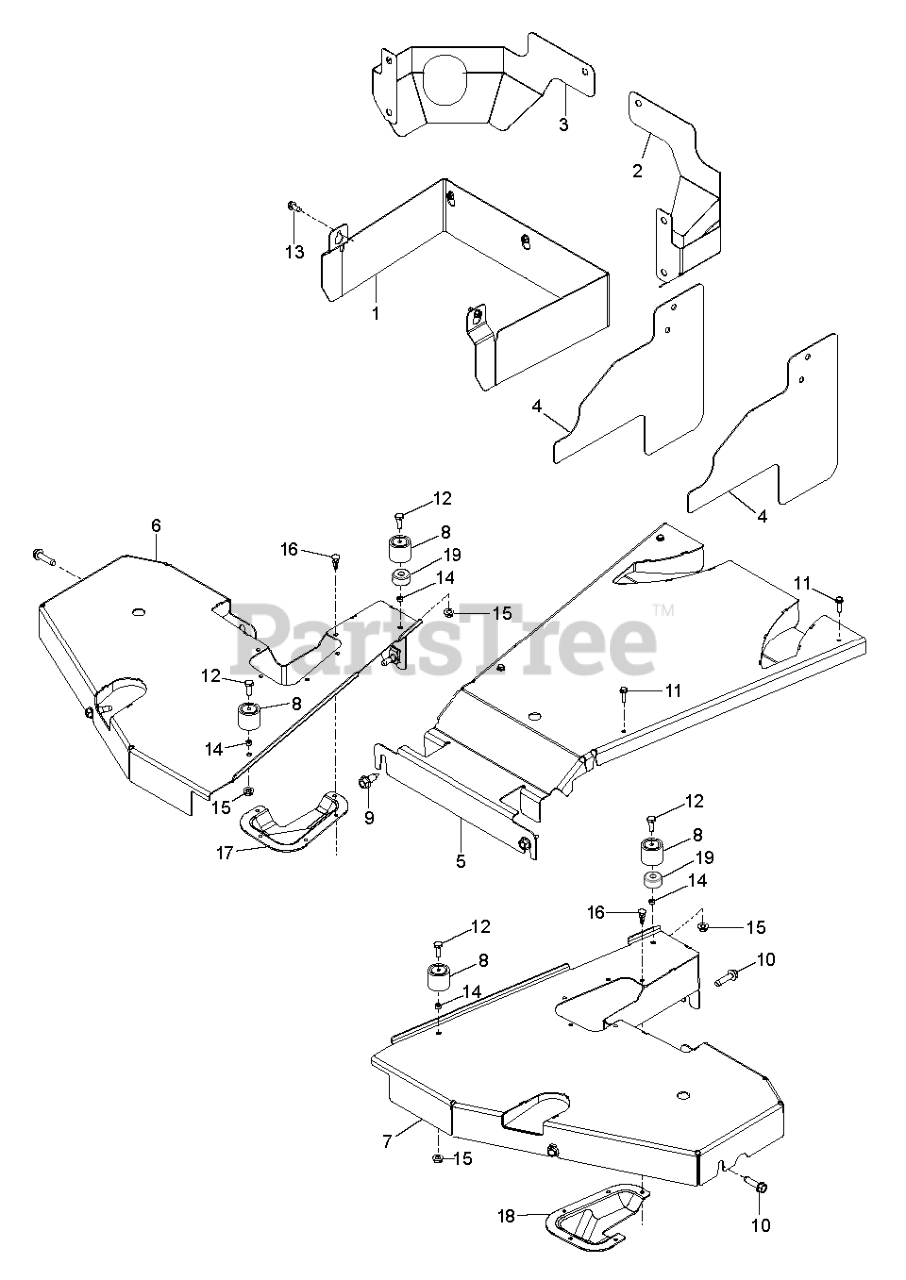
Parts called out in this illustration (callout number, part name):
1	GUARD CLUTCH COVER BLACK X428
2	GUARD MUFFLER LEFT - BLACK X4
3	GUARD MUFFLER RIGHT - BLACK X
4	GUARD SIDE TRANSMISSION BLACK
5	GUARD MID DECK MANDREL COVER W
6	GUARD.PNT.WLD.CVR.MANDRL.LT.GY
7	GUARD.PNT.WLD.CVR.MANDRL.RT.GY
8	HOLDER.ASM.STEM.BASE.WASHER
9	SCREW 3/8-16X1
10	SCREW.SHAKEPROOF.1.25.BLACK
11	SCREW M6SF 5X20
12	Bolts
12	HCS 1/4-20.
13	SCREW.1/4-20X5/8
14	NUT M6M M5
15	NUT HEX_LRG FLG_1_4-20_LOCK
15	JAM NUT 1/4C (2 2 PW01)
19	Spacers
